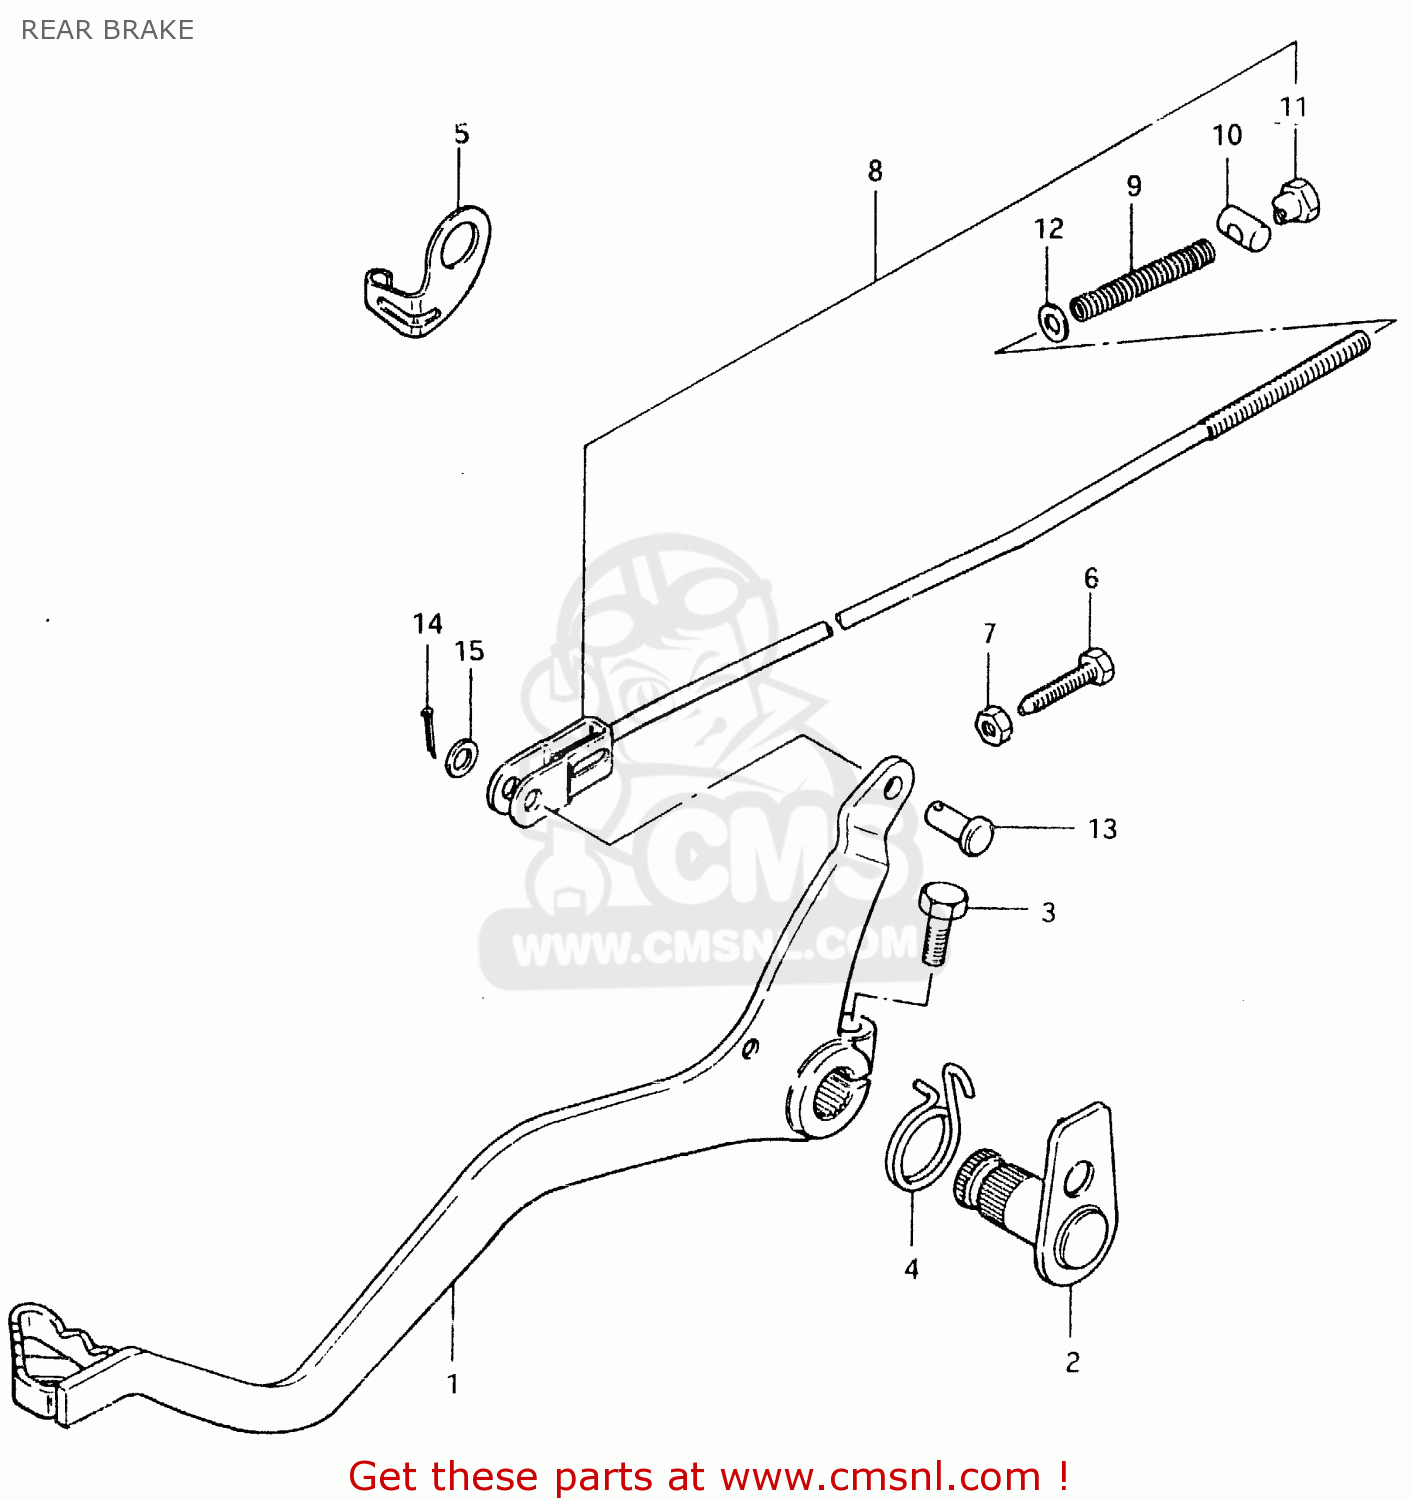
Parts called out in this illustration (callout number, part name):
1	PEDAL,BRAKE
2	ARM,BRAKE PEDAL
3	BOLT
4	SPRING
5	HOOK,STOP LAMP SWITCH SPRING
6	BOLT(6X23)
7	NUT
8	ROD ASSY,RR BRAKE
9	SPRING
10	PIN
11	NUT
12	WASHER
13	PIN(L:13.5)
14	PIN 20X20
15	WASHER
